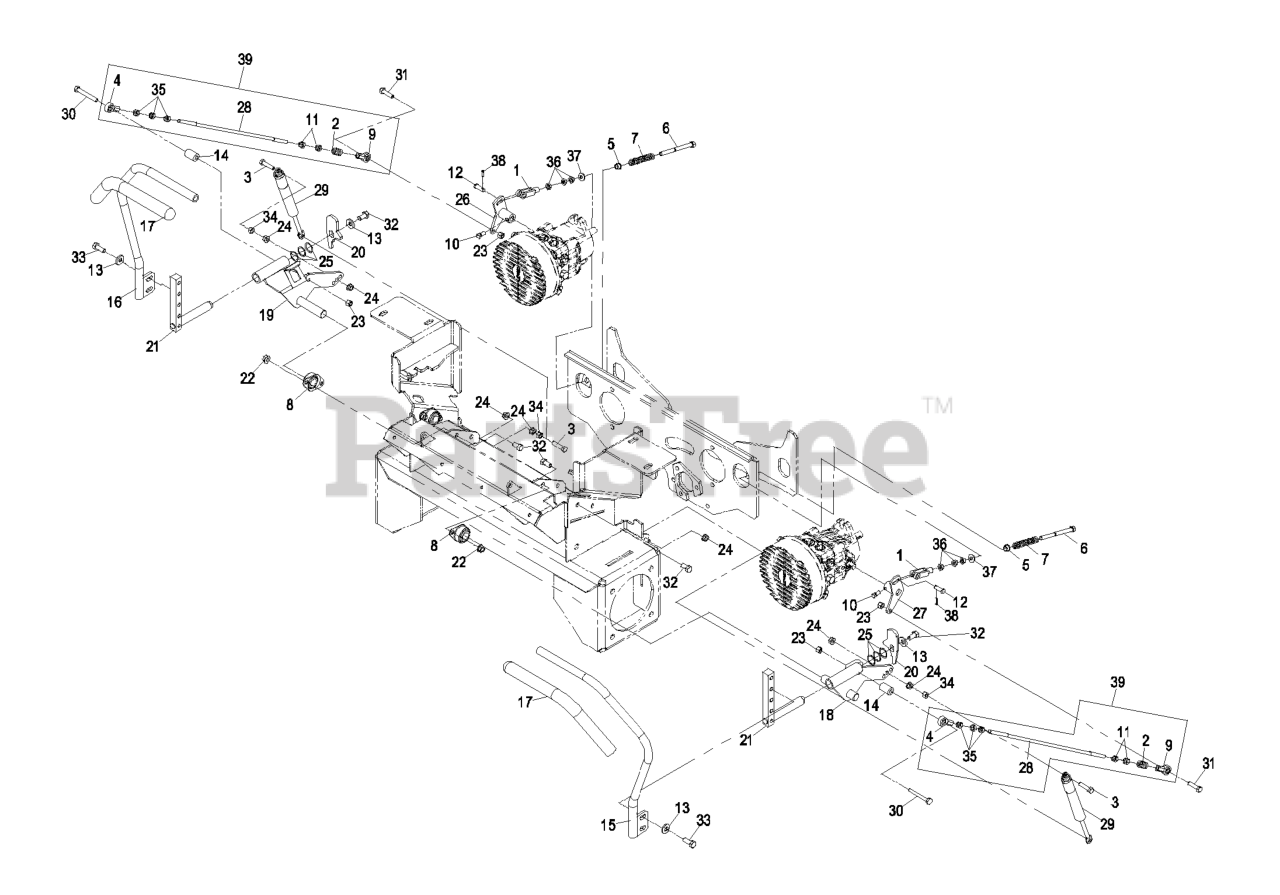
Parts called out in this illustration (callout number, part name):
1	YOKE-ADJUSTABLE
2	SPRING-COMPRESSION
3	SCREW-HH
4	BALLJOINT-RH
5	BUSHING-FLANGED
6	BOLT-RETURN, NEUTRAL
7	SPRING-RETURN, NEUTRAL
8	BEARING-FLANGE, SIDE
9	BALLJOINT-LH
10	SCREW-SET
11	NUT
12	PIN-CLEVIS
13	WASHER-BELLEVILLE
14	SPACER-HYDRO CONTROL, LH
15	ASM,LH LEVER/GRIP
16	ASM.RH LEVER/GRIP
17	GRIP,CONTROL LEVER
18	WLD,LH FMZ MOTION CTRL (P
19	WLD,RH FMZ MOTION CTRL(PL
20	TAB,FMZ MOTION CNTRL (PLA
21	WLD,FR CONTROL SHAFT(PLTD
22	NUT-HHF, WHIZ
23	NUT-LOCK, NI
26	WLD,PJ PUMP CONTROL RH
27	WLD,PJ PUMP CONTROL LH
28	ROD,TRACKING FMZ (PLTD)
29	DAMPER-CONTROL, MOTION
30	SCREW-HH
31	SCREW-HH
32	SCREW-HH
33	SCREW-HH
34	NUT-HEX
35	NUT-HEX
36	NUT-JAM
37	WASHER-FLAT
38	PIN-COTTER
39	ASM,FMZ PJ TRACKING ROD
